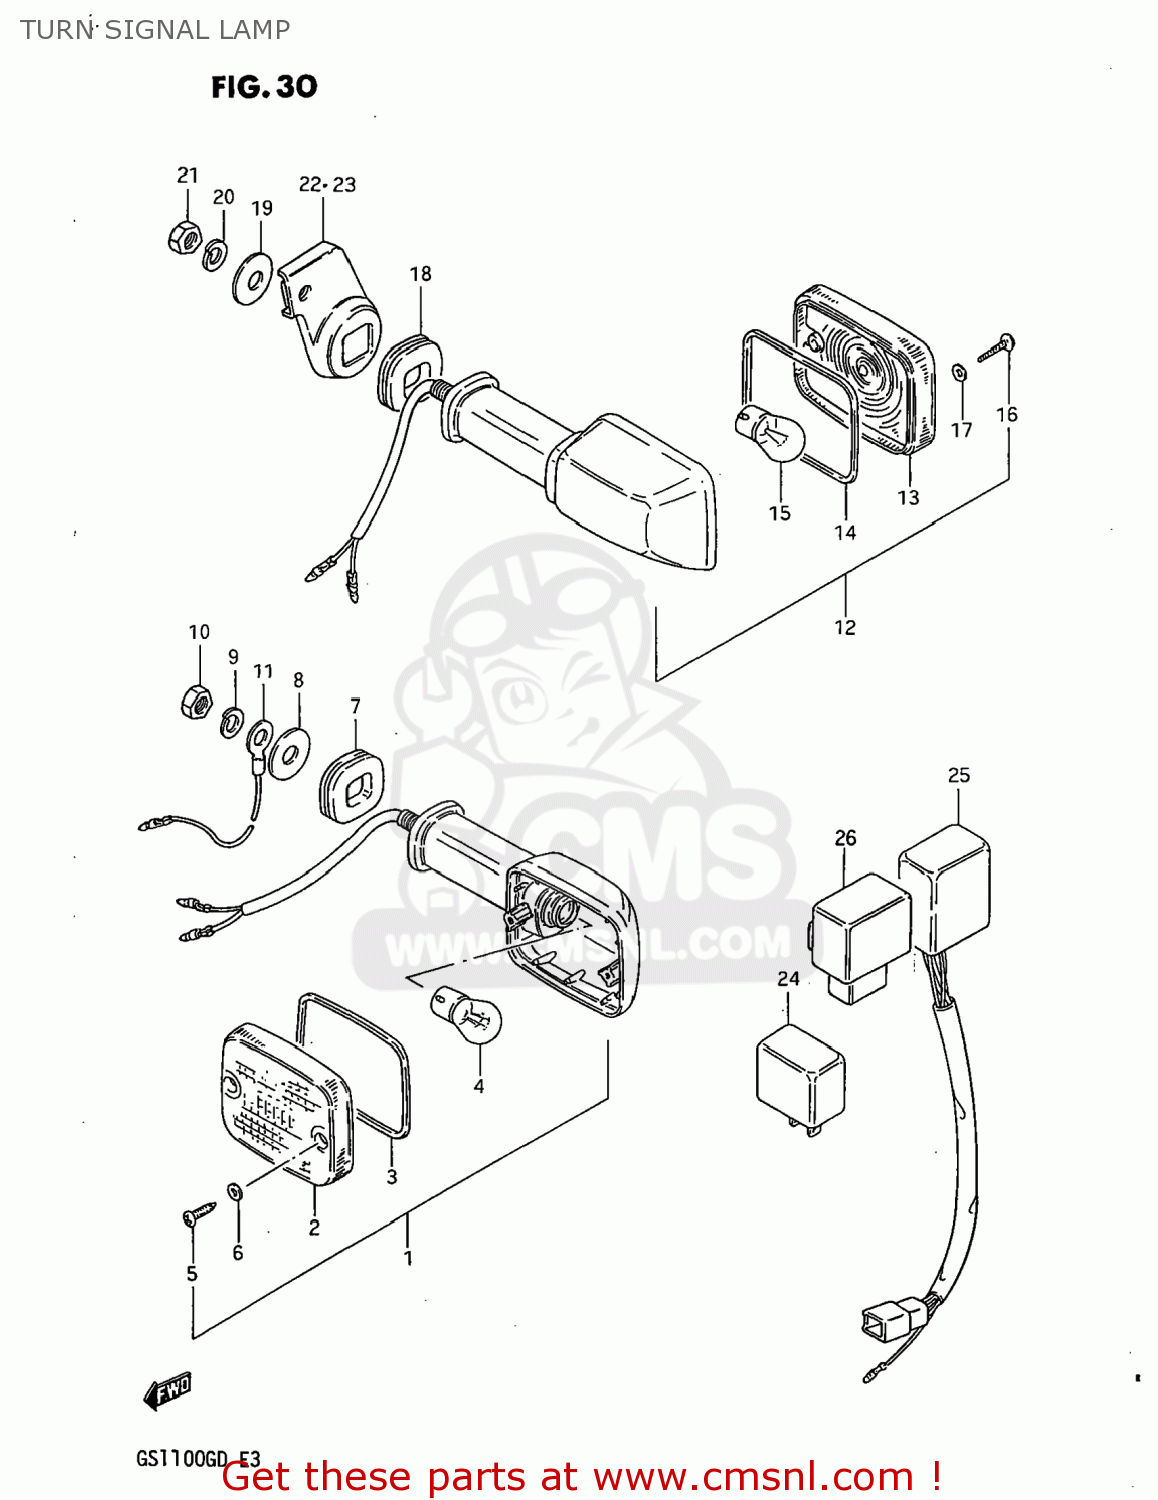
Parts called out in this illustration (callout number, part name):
1	LAMP ASSY,FR TURN SIGNAL
2	LENS
3	GASKET (NAS)
4	BULB(12V23W)
5	SCREW
6	GASKET (NAS)
7	CUSHION
8	WASHER (10.5X30X2.3)
9	LOCK WASHER
10	NUT
11	WIRE
12	LAMP ASSEMBLY,FRONT TURN SIGNAL
13	LENS
14	GASKET (NAS)
15	BULB(12V23W,STANLEY,A4577A)
16	SCREW
17	GASKET (NAS)
18	CUSHION
19	WASHER (10.5X30X2.3)
20	LOCK WASHER
21	NUT
22	BRACKET,REAR TURN SIGNAL
23	BRACKET,REAR TURN SIGNAL
24	RELAY ASSY,TURNSIGNAL
25	UNIT,TURN SIGNAL CONTROL
26	UNIT,TURN SIGNAL CONTROL
